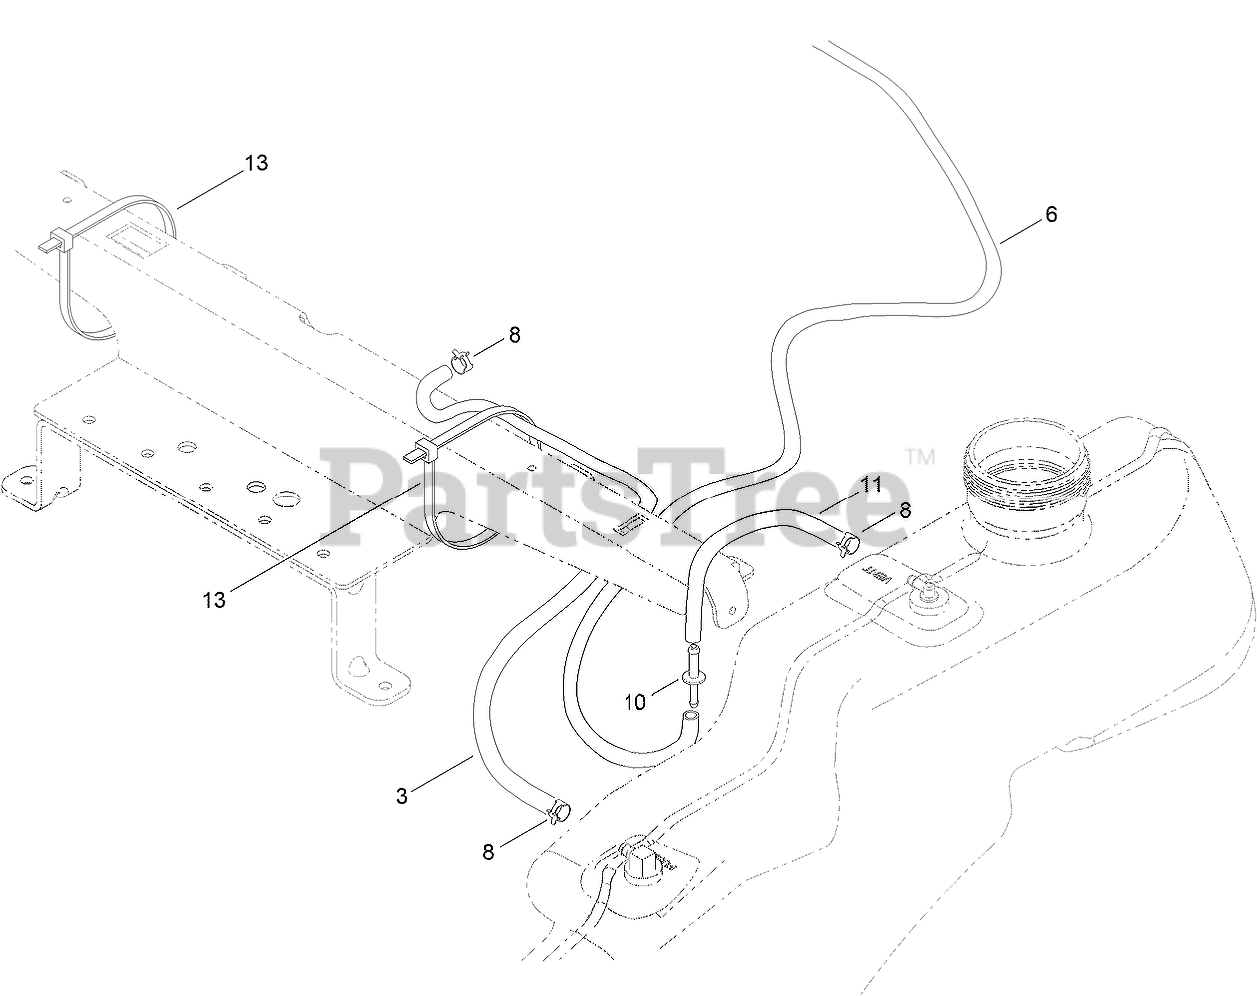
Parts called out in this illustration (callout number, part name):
3	HOSE-FUEL
6	HOSE-FUEL
8	CLAMP-HOSE
10	ADAPTOR-ORIFICE
11	HOSE-FUEL
13	TIE-CABLE
